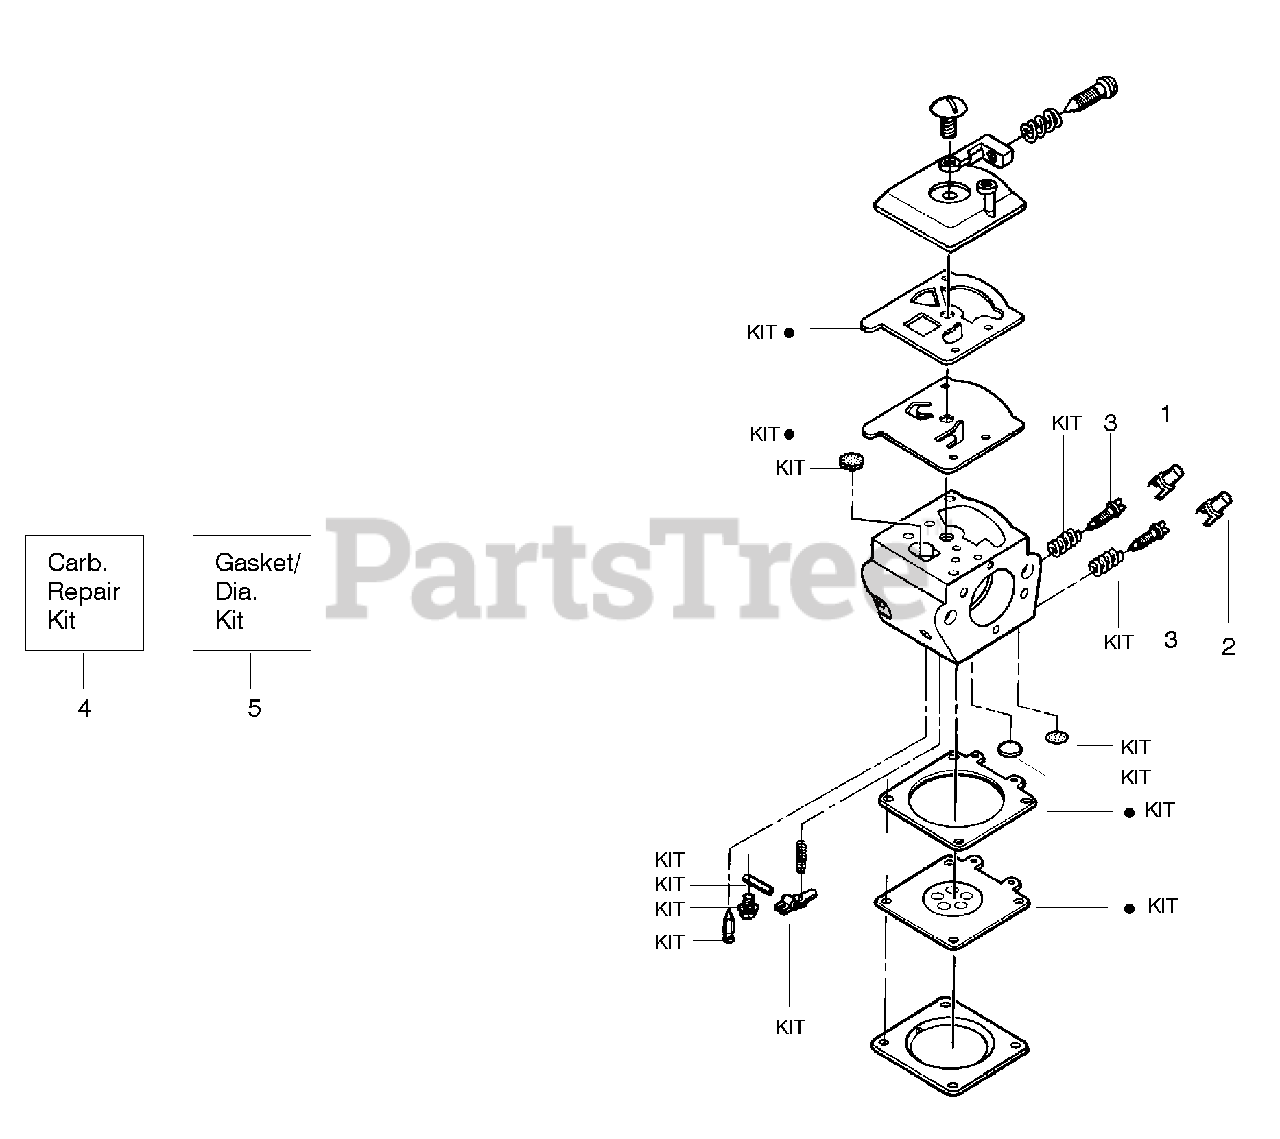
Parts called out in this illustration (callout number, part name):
1	Limiter Cap-High (Brown)
2	Limiter Cap-Low ( Tan)
3	Needle-high/low speed
4	Kit-Carburetor Repair (KIT= Indicates Contents)
5	Kit-Gasket Diaphragm (Indicates Contents)
